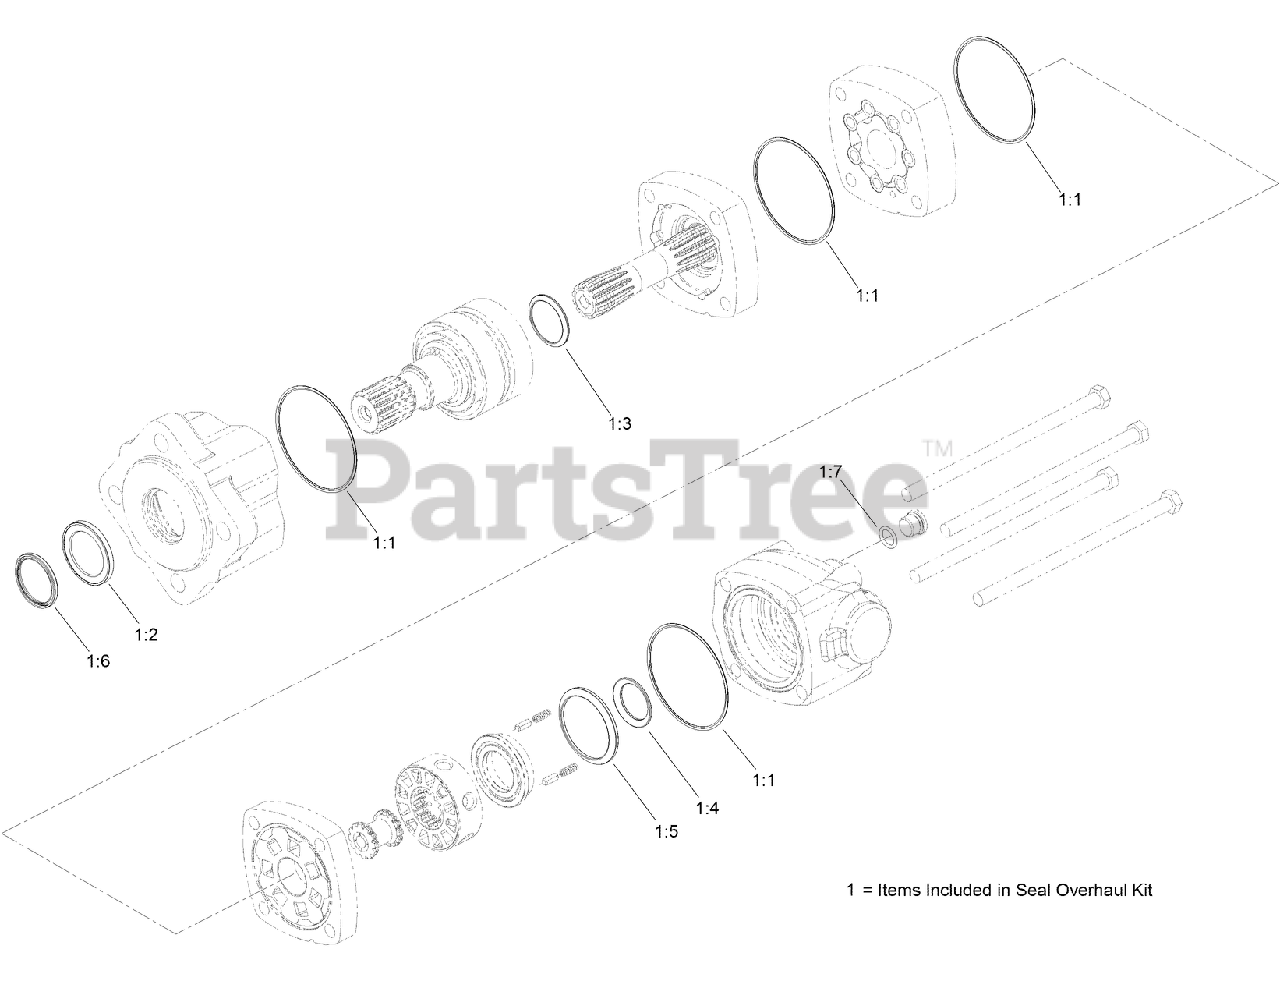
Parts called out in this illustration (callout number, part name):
1	SEAL KIT
1:1	SEAL
1:2	SEAL-SHAFT, HIGH PRESSURE
1:3	Deck ASM
1:4	Deck ASM
1:5	Deck ASM
1:6	Deck ASM
1:7	Deck ASM
